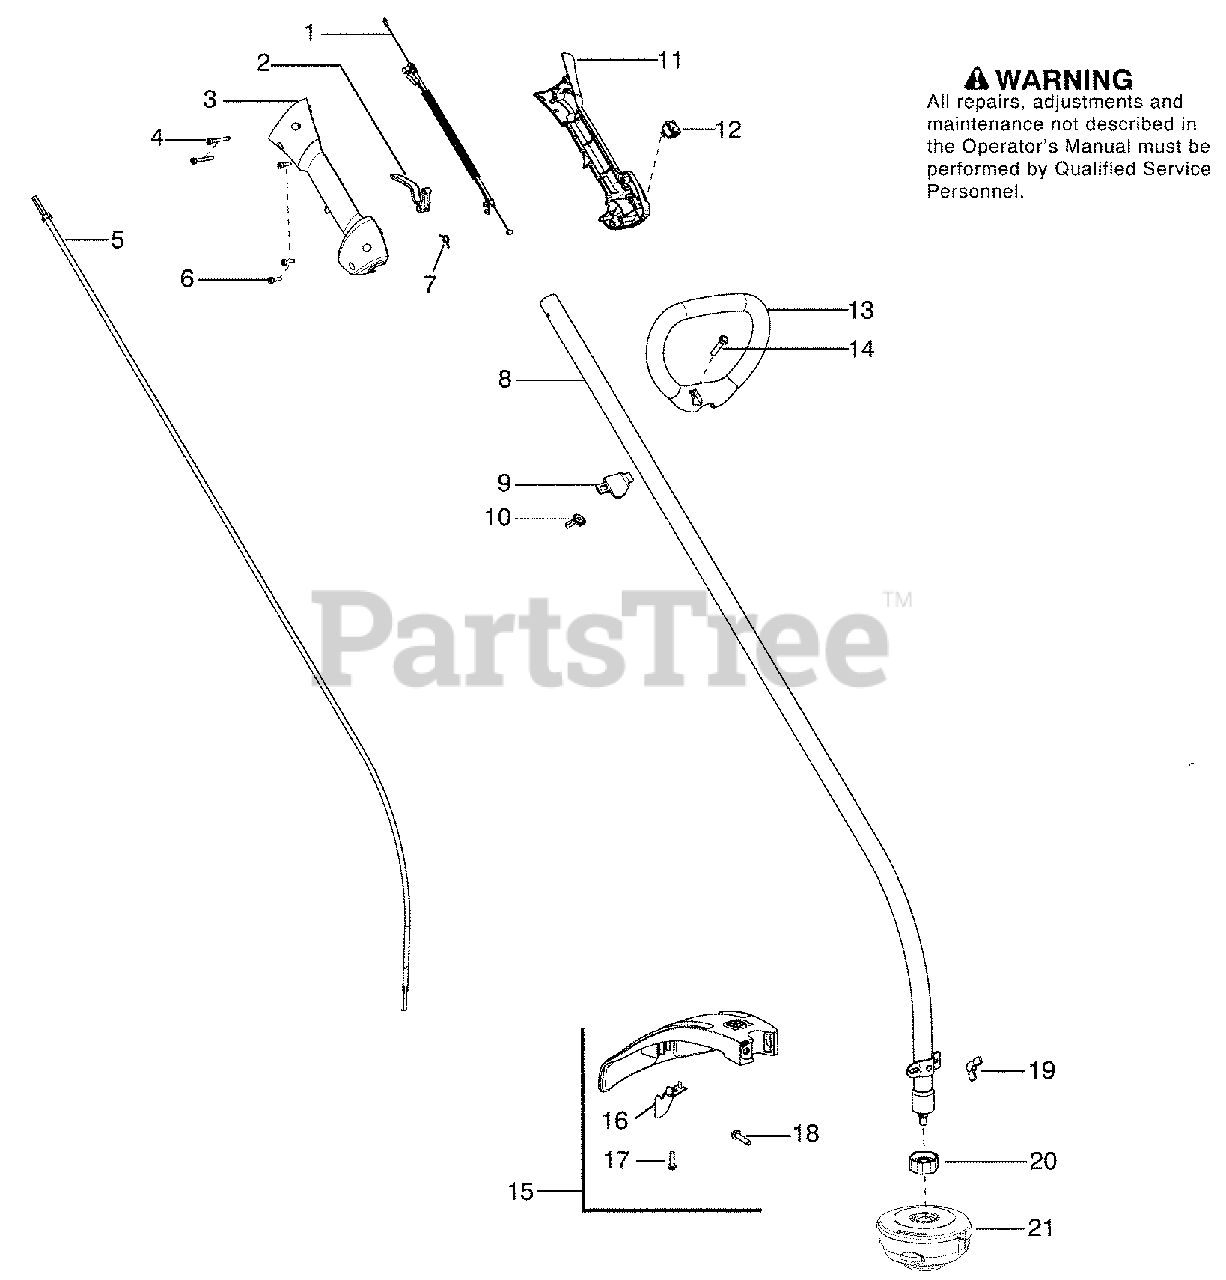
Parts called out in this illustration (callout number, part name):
1	Assy-Cable/Wire Harness from SN New Part Number For This IPL
3	Housing-Throttle (RH)
5	Flexshaft from SN New Part Number For This IPL
7	Spring-Trigger
8	Kit-Driveshaft
9	Clamp-Handle
10	Wingnut
11	Housing-Throttle (LH)
12	Kit-Switch
13	Handle-Assist
15	Kit-Shield
16	Kit - Limiter-Line
19	Wingnut
21	Assy-T25 Cutting Head
